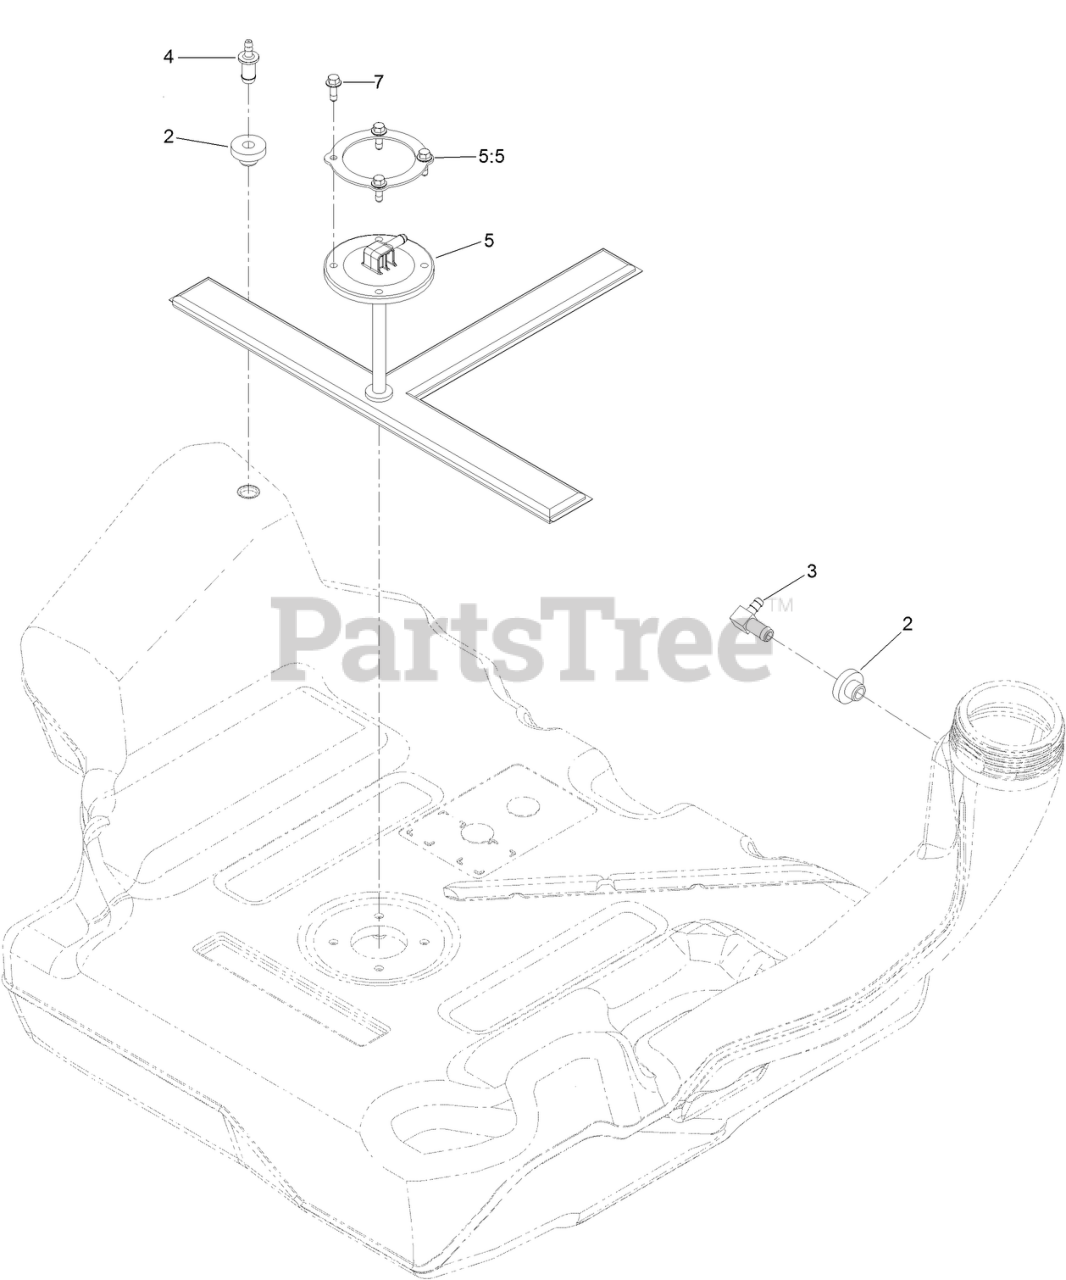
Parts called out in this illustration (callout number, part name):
2	BUSHING
3	FITTING-90 DEG
4	FITTING-ORIFICE, STRAIGHT
5	PICKUP-FUEL
5:5	RING-RETAINER
